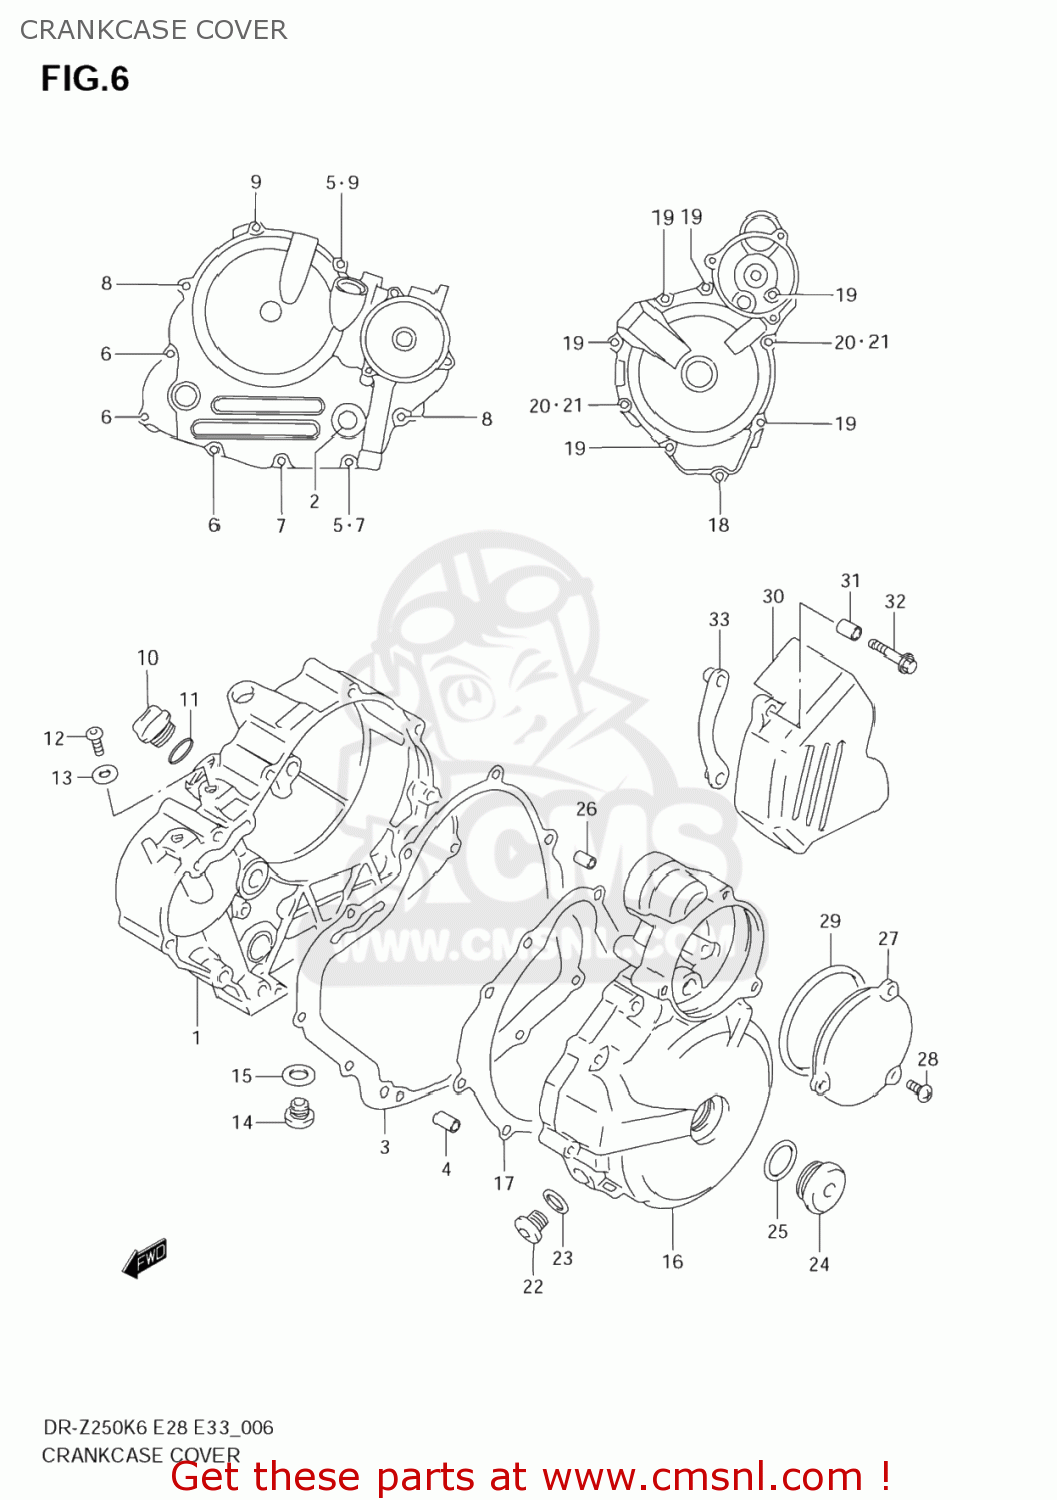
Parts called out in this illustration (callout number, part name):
1	COVER,CLUTCH
2	LENS,OIL LEVEL CHECK
3	GASKET,CLUTCH COVER
4	PIN
5	GASKET(5.8X13X1.2) (NAS)
6	BOLT
7	BOLT
8	BOLT
9	BOLT
10	PLUG
11	O RING(D:3.1,ID:16.8)
12	PLUG,14X12
13	GASKET(13.8X18.8X4.8) (NAS)
14	PLUG(10X10)
15	GASKET(10X14X3.6) (NAS)
16	COVER,MAGNETO
17	GASKET,MAGNETO COVER
18	BOLT
19	BOLT
20	BOLT
21	GASKET(5.8X13X1.2) (NAS)
22	PLUG,14X12
23	GASKET(13.8X18.8X4.8) (NAS)
24	PLUG(26X9)
25	O RING(D:3.1,ID:22.7)
26	PIN
27	COVER,STARTER IDLE GEAR
28	SCREW
29	O RING(D:2.6,ID:69.6)
30	COVER,ENGINE SPROCKET
31	SPACER(6.5X10X11.5)
32	BOLT
33	PLATE,FR CHAIN GUIDE
